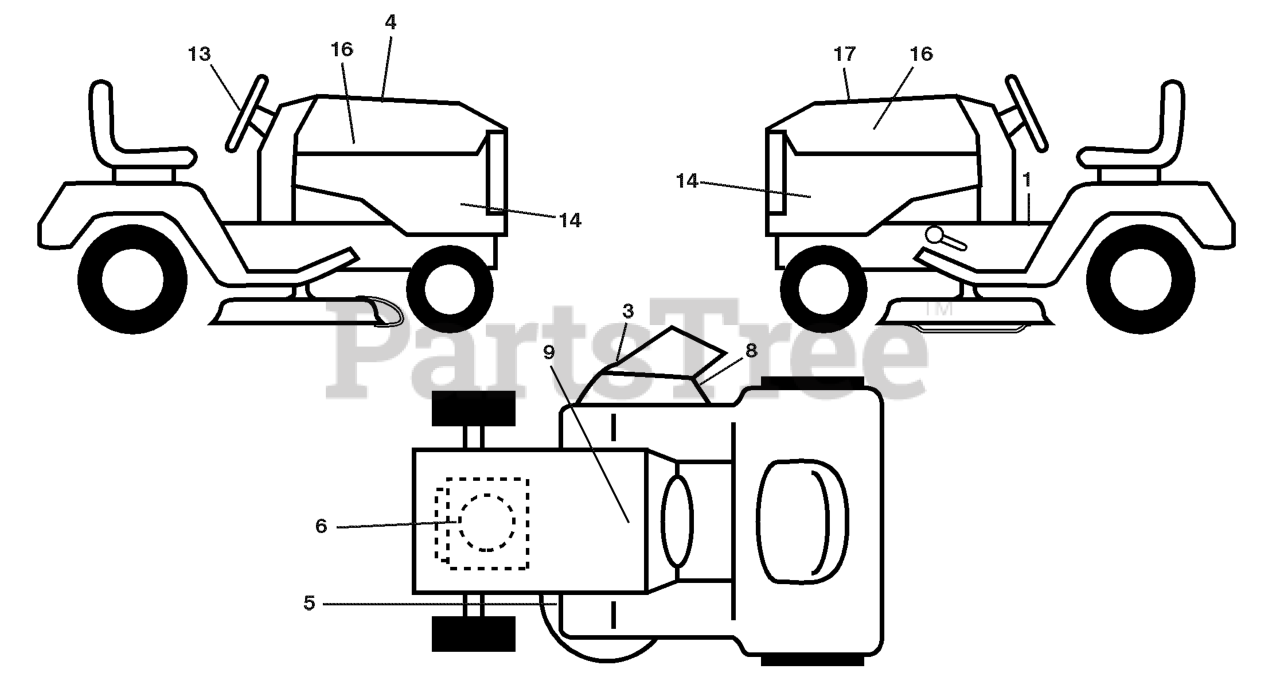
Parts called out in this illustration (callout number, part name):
1	DECAL.FENDER.WARNING.ENG
3	DECAL.WARN.KEEP.HAND.AWAY
4	DECAL HOOD CUST. RESP.
5	DECAL CLUTCH/BRAKE
6	DECAL, ENG. HP
8	DECAL.MOWER.SCH.48/54
9	DECAL BTRY SYMBOLS
13	DECAL.WHEEL.STRG.LGN.H
14	DECAL, PANEL SIDE
16	DECAL.HOOD.LOGO.HUSQVARNA
17	DECAL.RPL.BS.26INTK.TGW.54E.TT
17	DECAL.BYPASS.FENDER.CRD.LT.YT
17	PAD.FOOTREST.LH.HUSQ.T
17	PAD.FTRST.RH.PCH.HUSQ.
17	Manual, Owner's
